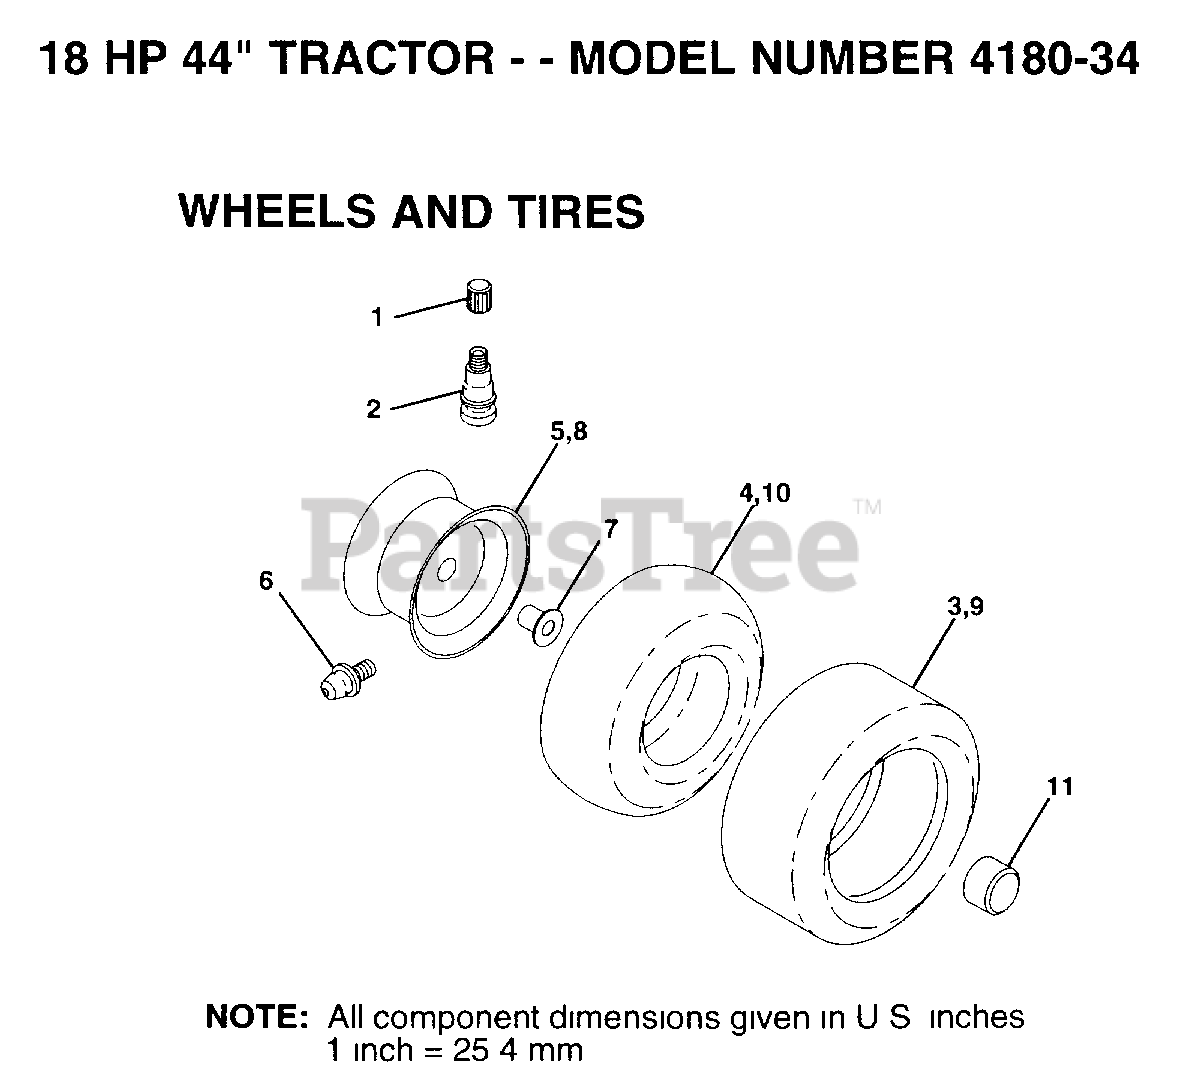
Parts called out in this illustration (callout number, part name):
1	VALVE CAP
2	VALVE STEM LT
4	TUBE.5.3/4.5/6
6	FITTING LT
7	"FLANGE, BEARING"
10	TUBE.23X8/10-12
11	HUB CAP
